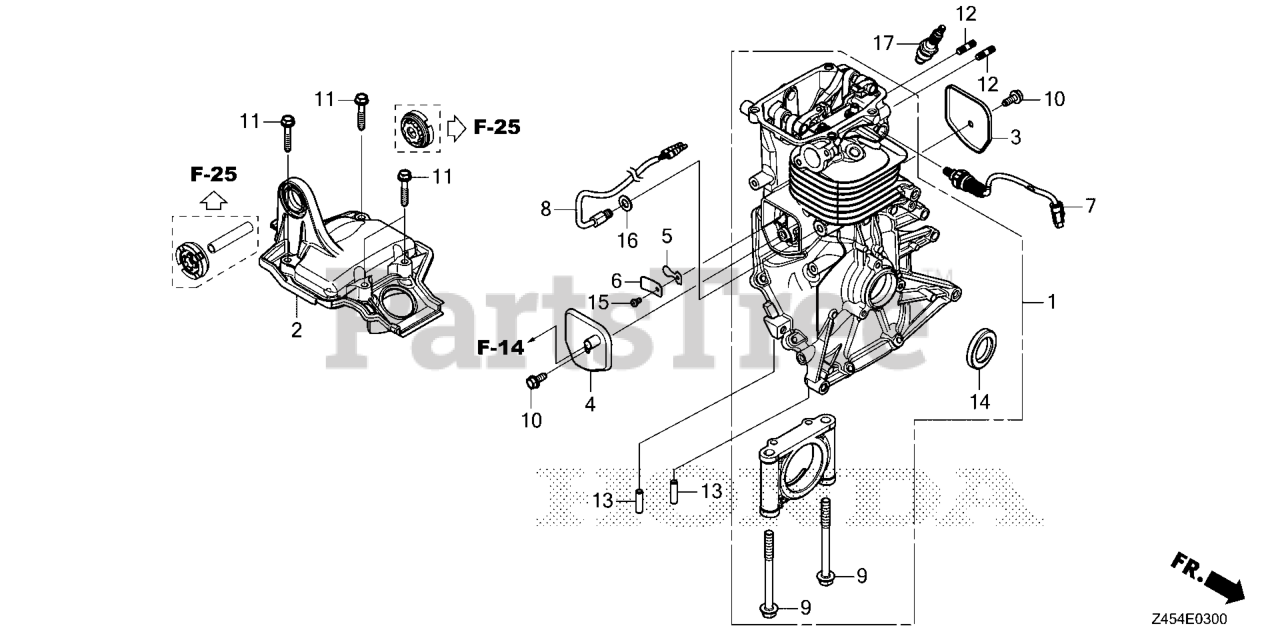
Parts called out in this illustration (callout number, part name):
1	BARREL, CYLN (0000)
2	COVER, HEAD
3	COVER A, BREATHER
4	COVER COMP B
5	VALVE, OIL OUTLET
6	PLATE, STOPPER
7	SENSOR, OXYGEN
8	SENSOR ASSY., TE
9	BOLT, FLANGE (8X90)
10	BOLT, FLANGE (6X14)
11	BOLT, FLANGE (6X32)
12	BOLT (6X18) (CT200)
13	PIN, DOWEL (6X22.5)
14	OIL SEAL (22X35X6)
15	SCREW, PAN (3X5)
16	WASHER, PLAIN (8MM)
17	SPARK PLUG (CR6HSB)
